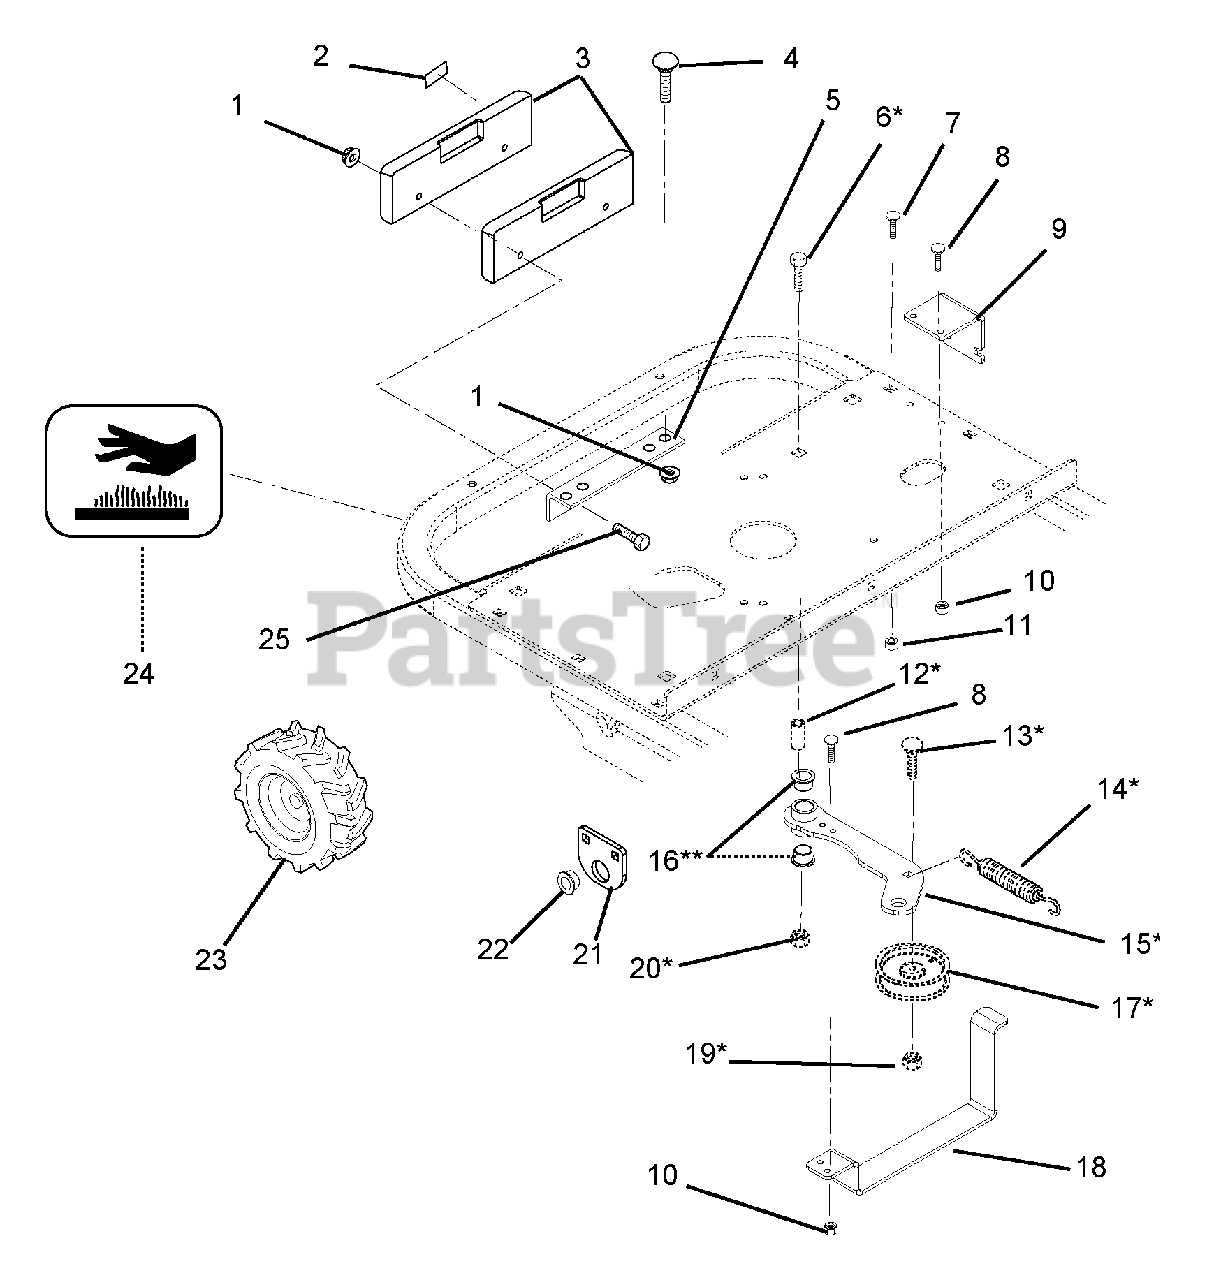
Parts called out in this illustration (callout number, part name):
1	@NUT-LK-TOP-FLG .38-16 YWZC
2	REFLECTOR,TAIL(AGRI-FAB)
3	WEIGHT, CAST IRON
4	@BLT-RDHDSQNK .38-16X2.50 G5YZ
5	BRKT,ANGLE
6	@BLT-HEX .50-13X2.50 GR5 YWZC
7	@BLT-RDHDSQNK .38-16X2.00 G2YZ
8	@BLT-HEX .25-20X.75 GR5 YWZC
9	LATCH,COLD START
10	@NUT-LK-TOP-FLG .25-20 YWZC
11	@NUT-LK-CTR-JAM .375-16 YWZC
12	BSHG-SLV .500X.750X1.560
13	@BLT-RDHDSQNK .38-16X1.25 G5YZ
14	SPRING, EXT
15	WMT, IDLER ARM
16	BSHG-FLG 0.75X0.875X.625X1.125
17	IDLER-FLAT 4.00 X .38 NWHAMSHR
18	HANDLE,COLD START
19	@NUT-LK-CTR-JAM .375-16 YWZC
20	@NUT-LK-TOP-FLG .50-13 YWZC
21	BRACKET,REAR PIVOT
22	BSHG-FLG 1.000X1.12X.62X1.50BR
23	ASSY,WHEEL & TIRE 18X6.5 S-HOG
24	DECAL, HOT SURFACE
25	@BLT-HEX .38-16X4.50 GR5 YWZC
